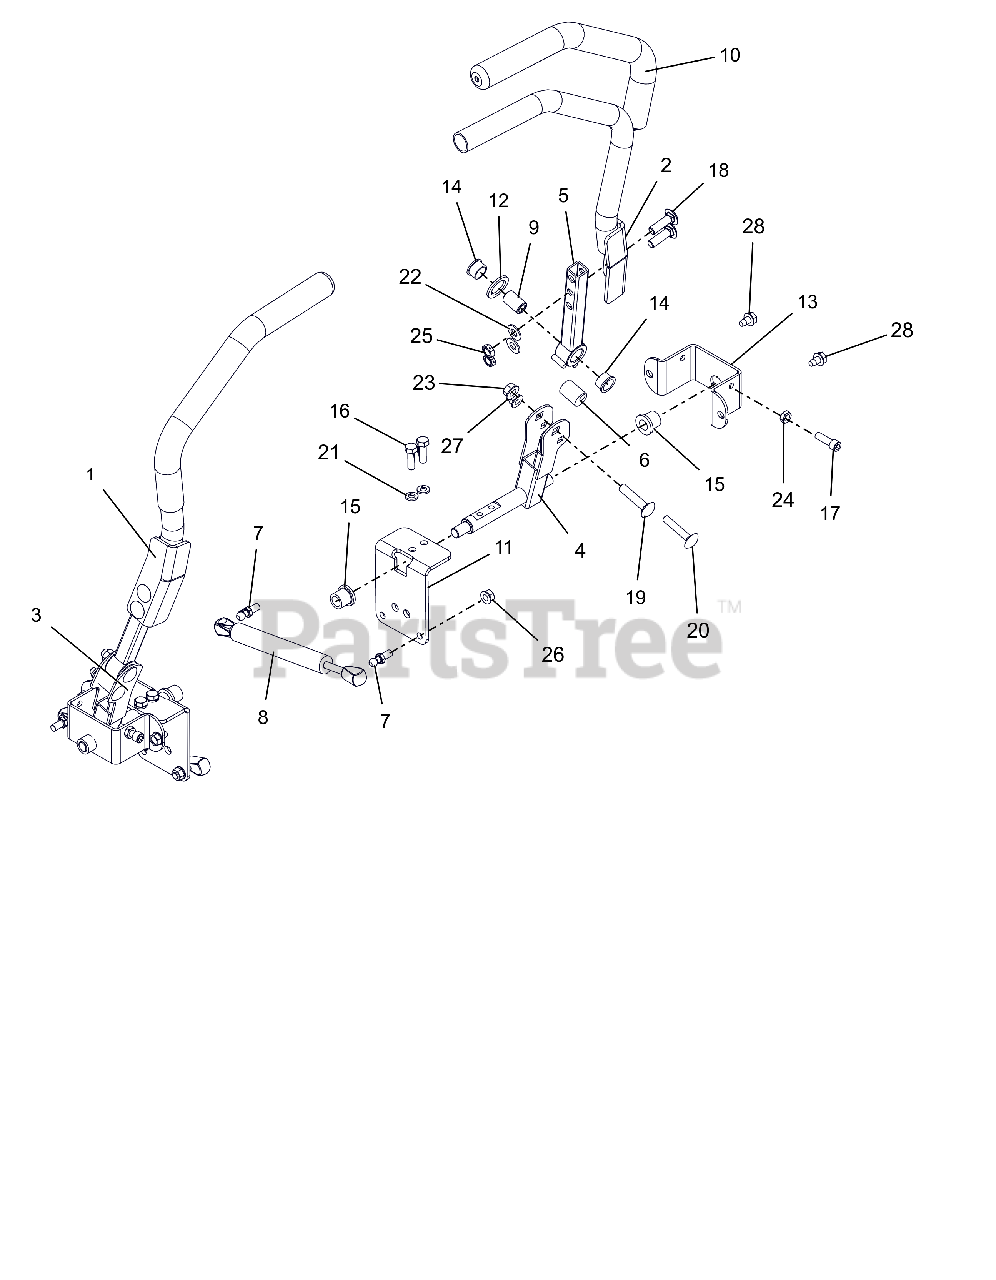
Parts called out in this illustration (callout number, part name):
1	WLDMT, STEERING HANDLE RH
2	WLDMT, STEERING HANDLE LH
3	WLDMT,STEERING ARM LOWER RIGHT
4	WLDMT,STEERING ARM LOWER LEFT
5	WLDMT, UPPER CONTROL ARM
6	BSHG,ECCEN .328X.750X1.01 PM
7	STUD- BALL
8	DAMPER, STABILUS
9	SPACER, .375X.625X.970 (PM)
10	GRIP, HANDLEBAR 15" FOAM
11	BRKT, STEEERING
12	WASHER, FRICTION .875X1.25X.10
13	BRKT, STEERING
14	BSHG-FLG, .625X.75X.450X.875
15	BSHG-FLG .515X.750X.745X1.00NY
16	BLT, HEX .31-18X1.00 G8 ZCC
17	SCR, SKH .312-18X1.00 G8 SS
18	BLT,RHSSN .38-16X1.25 G5 BFP
19	BLT,RHSSN .38-16X1.75 G5 BFP
20	BLT,RHSSN .31-18X1.75 G5 BFP
21	WSHR,LK-REG .312X.078 ZCC
22	WSHR,FLT .406X.812X.065 ZCC
23	NUT-LK-CTR-FLG .375-16 GF ZCC
24	NUT-JAM .312-18 G2 ZCC
25	@NUT-LK-CTR-JAM .375-16 YWZC
26	NUT-LK-TOP-FLG .312-18 GF ZCC
27	NUT,LK-NYL-FLG .31-18 G5ZC120
28	SCR,TAP .312-18X.50 HWH TR ZCC
